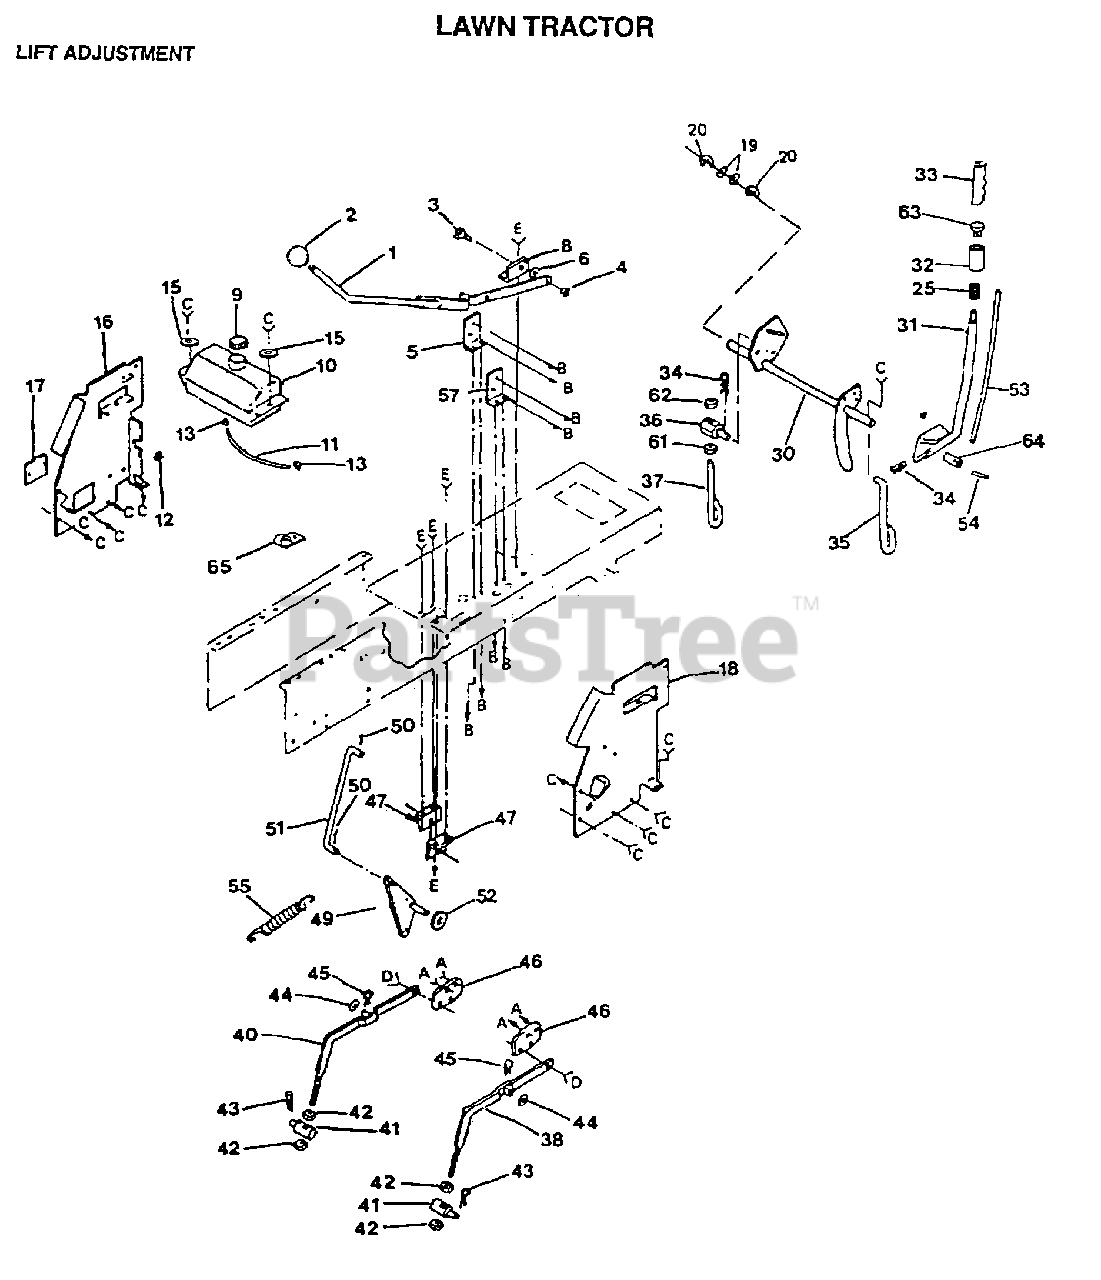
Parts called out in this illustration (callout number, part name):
3	"BOLT, SHOULDER LT"
5	"BRACKET,SWITCH LT"
8	"SUP,LVR,CLUTCH LT"
10	TANK.FUEL.LT.
11	FUEL LINE T
12	SNAP BUSHING T
13	HOSE CLAMP
15	WASHER GT
17	COVER ACCESS
18	"PANEL,DASH RH"
19	WASHER
20	E-RING
25	SPRING T
31	LEVER ASSY LT
33	GRIP
35	LIFT LINK LT
37	PIVOT PIN T
38	RH SUSP ARM ASM
40	LH SUSP ARM ASM
42	NUT
43	SPRING H
45	SPRING.RETAINER
46	"BRACKET, SUSPE T"
47	"BRKT,BELLCRAN T"
49	"T, BELLCRANK"
50	COTTER PIN
51	ROD CLUTCH T
52	WASHER
54	PIN-GROOVE LT
57	BRACKET LT
61	NUT
64	COUPLE LEVER T
65	INSUL CLIP T
